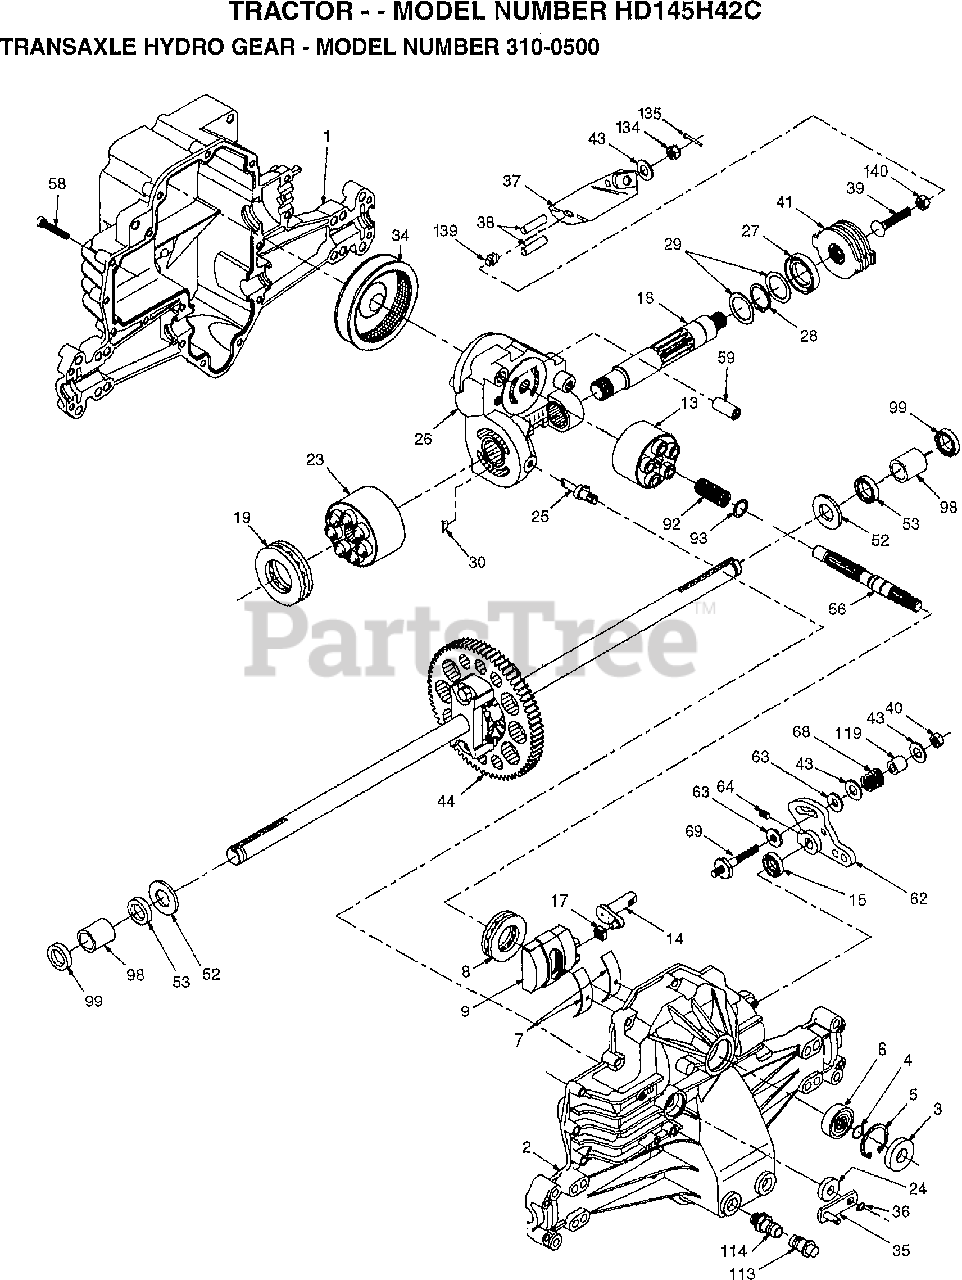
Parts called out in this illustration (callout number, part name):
1	HOUSING.L.44863RM
2	HOUSING.UPR.70122
3	SEAL.9008000-0128
4	RING.RET.2003016.
5	RING.RET.2003052.
6	BEARING.(50552)42X68X16
7	CRADLE- 2003023.
8	BEARING.THU.50551
9	SWASHPLT.2003087.
13	BLOCK.CLYN.70079.
14	ARM.TRUN.2003005.
15	SEAL.9008000-0126
17	GUIDE.2000015.
18	SHAFT.MOTOR.50449
19	BEARING.THU.50552
23	BLOCK.CYLIN.70082
24	SEAL.LIP.45074
25	ACTUATOR.2003555
26	KIT.CEN.SEC.70250
27	SEAL.LIP.45075
28	RING RETAIN 50007
29	WASHER.44872
30	PLATE.BYP.2003554
34	ELEMENT.OIL.44964
35	ARM.BYPASS.50270
36	RING.RETAIN.44870
37	ARM.ACTUAT.23710
38	PIN.ACTUAT.44891
39	BOLT.50316
40	NUT.LOCK.HX.50317
41	KIT.BRAKE.70135
43	WASHER HYD 44130
44	DIFFERNTIAL.70126
52	WASHER.HYD.44875
53	SEAL.HYDRO.45076
56	SHAFT.INPUT.50005
58	BOLT.1/4-20.44876
59	PIN.HYDRO.50002
62	ARM.CONTROL.50254
63	PUCK.DAMPER.50281
64	SCREW.SET.50018.
68	SPRING.HYD.50277
69	STUD.5/16-24.DANA
92	SPRING.2003014.
93	WASHER.2003017
98	BEARING.SLV.50137
99	SEAL.WIPER.50941
113	CAP.VENT.70109
114	O-RING.ASM.70110
119	SPACER.HYD.50278
134	NUT.CAS.HYD.44142
135	PIN.COT.HYD.44101
139	SPRING.COMP.50431
140	NUT.HEX.50269
